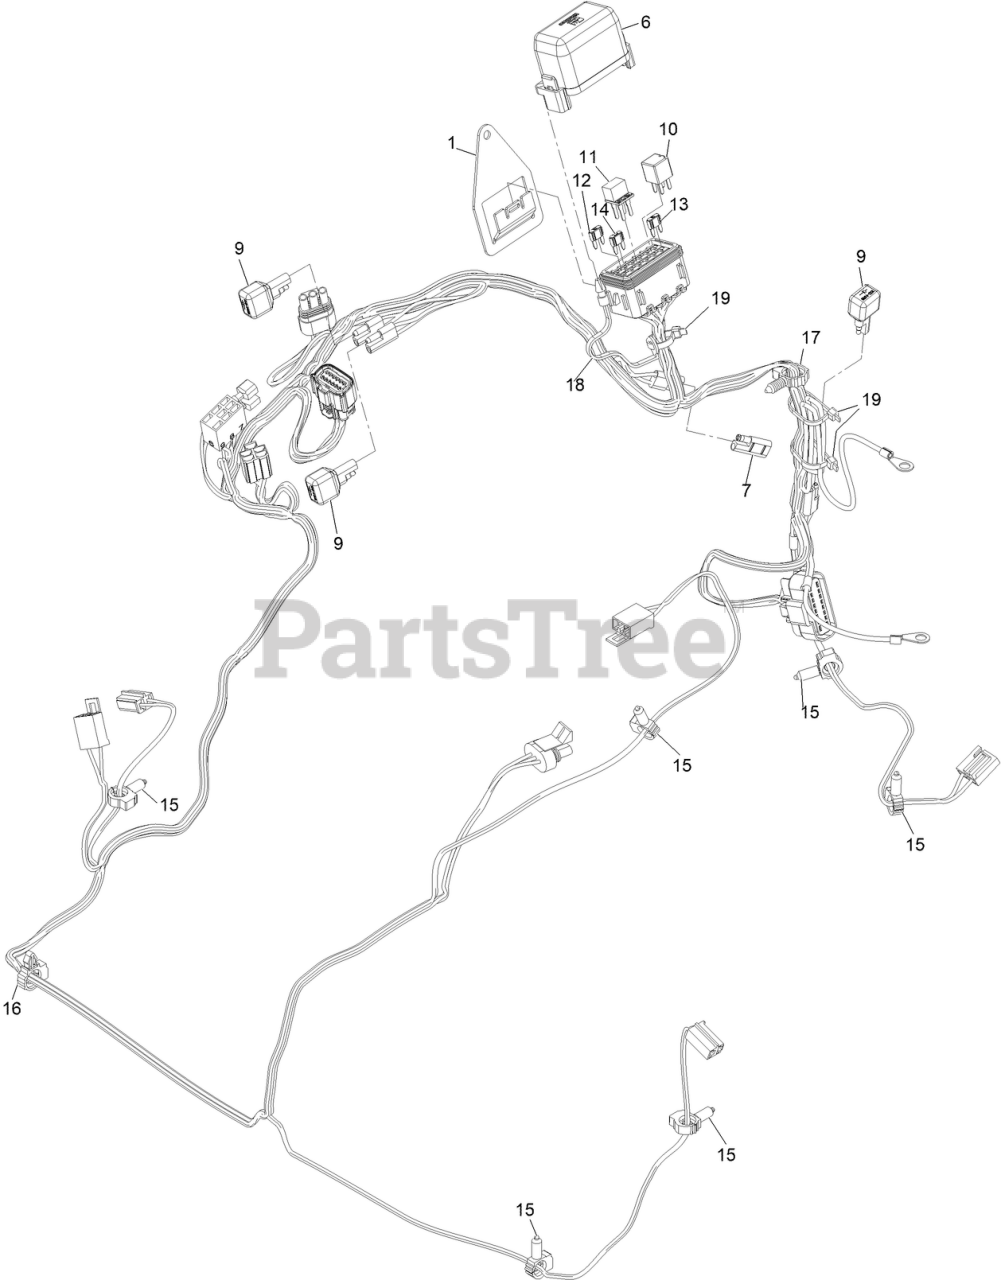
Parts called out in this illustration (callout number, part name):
1	BRACKET-LITTLEFUSE, PDM 18F
7	CAP-PLUG
10	RELAY-MICRO
11	RELAY-ENGINE IDLE, 10K
12	FUSE-MINI BLADE, 10 AMP
13	FUSE-MINI BLADE, 15 AMP
14	FUSE-MINI BLADE, 20 AMP
15	CLIP-HARNESS
16	Clip-Harness
17	Clip-Harness
18	Teather-Cap Littelfuse 18W
19	TIE-CABLE
